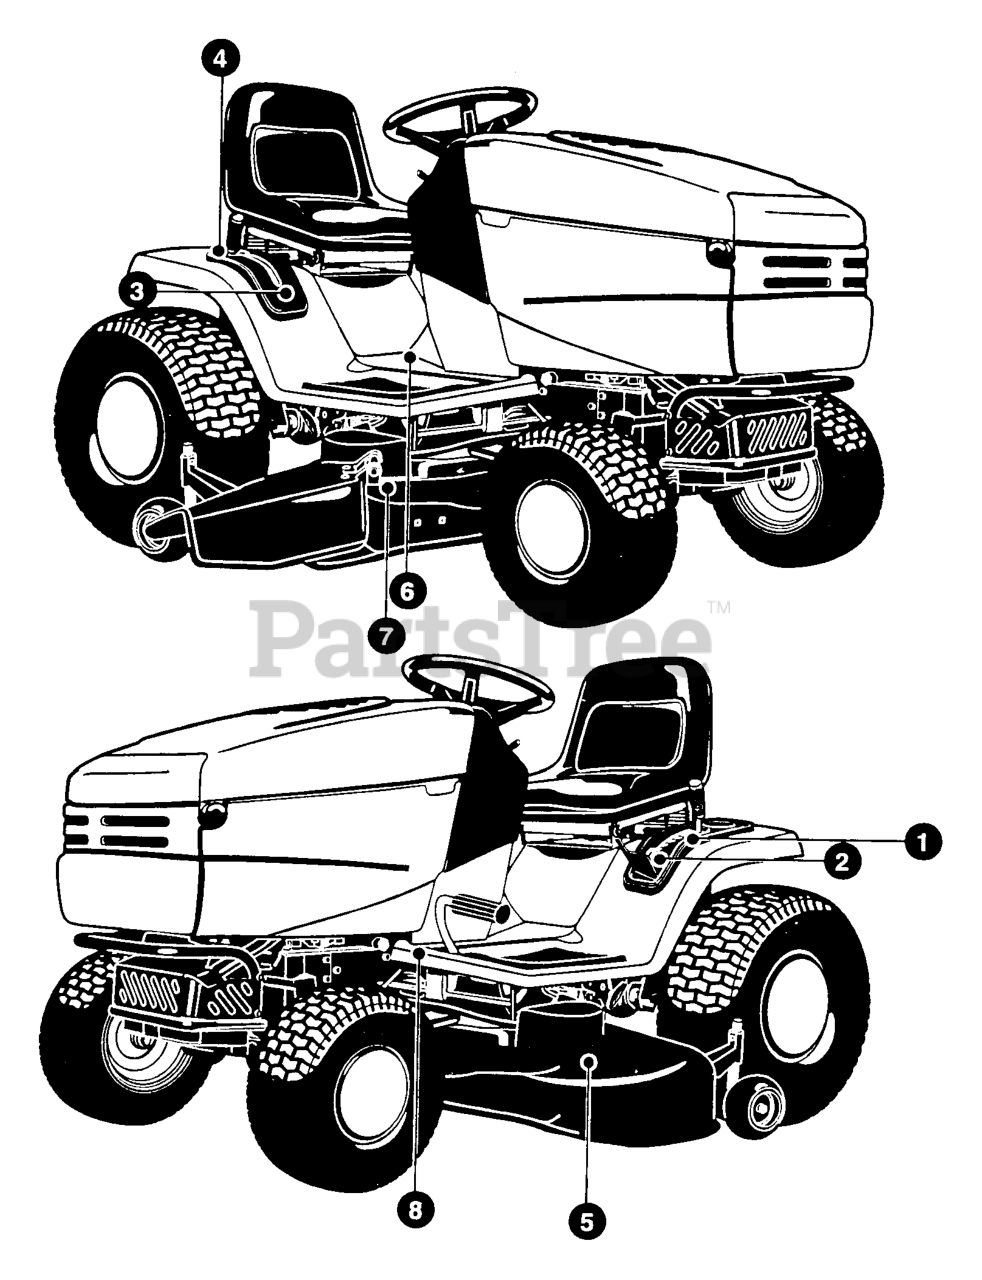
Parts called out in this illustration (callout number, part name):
1	DECAL, HEIGHT ADJUST 1-6
2	DECAL, DECK LEVEL
3	DECAL, SHIFT FENDER
4	DECAL, "R" FENDER
5	DECAL, NO STEP DOM WH/CLEAR
6	DECAL, INST CONS.
7	DECAL, DOM CUT FINGER/OPEI98
8	DECAL, CLUTCH/BRAKE TOE
